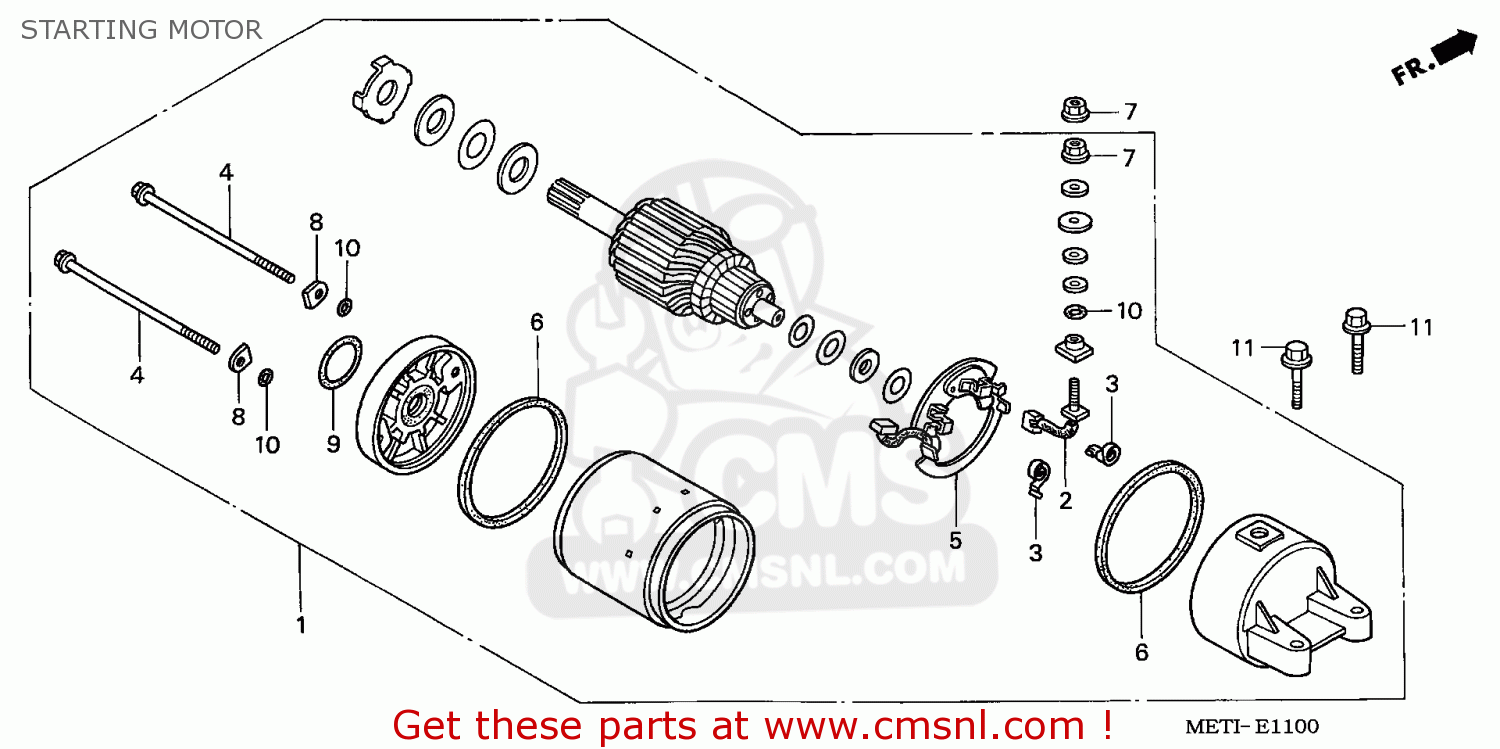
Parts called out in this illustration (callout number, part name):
1	MOTOR ASSY,STARTE
2	BRUSH,TERMINAL SE
3	SPRING,CARBON BUS
4	BOLT SET
5	BRUSH,HOLDER SET
6	RING
7	NUT-WASHER 6MM
8	WASHER,STEEL PLAT
9	O-RING,24.4X3.1
10	O-RING
11	BOLT,FLANGE,6X28
